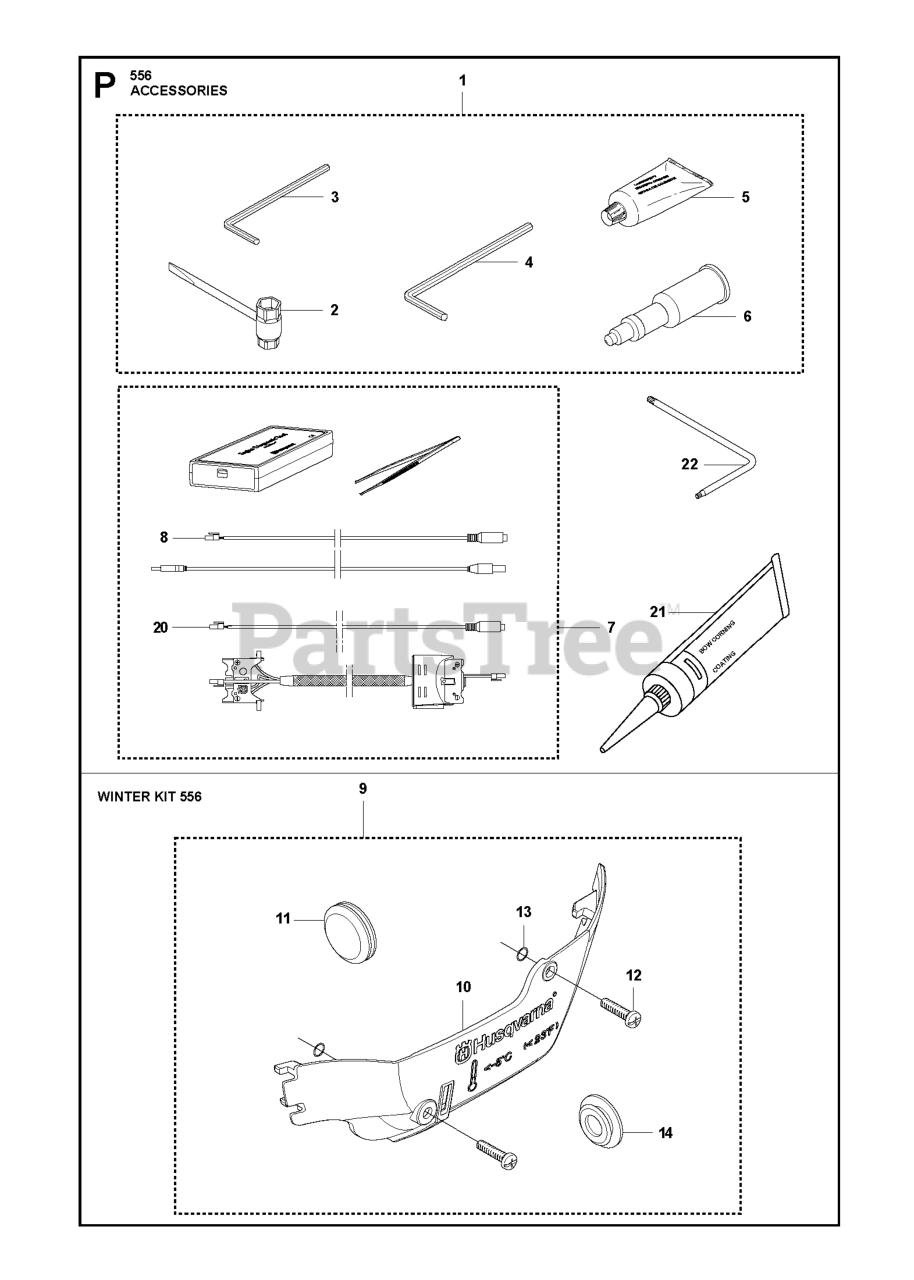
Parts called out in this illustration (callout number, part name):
1	WHEEL.STEER.HUSQ.SR.498.OVMLD
2	COMBINATION WRENCH
2	RP SUBASM.AXLE.CAST.NZTR.
4	SPINDLE WELDMENT.SPINDLE.LH.15
5	GREASE
5	SPINDLE WELDMENT.SPINDLE.RH.15
6	Grease Gun
6	THRUST WASHER
7	DIAGNOSTIC TOOL KIT
8	CABLE ASSY
9	WINTER KIT
9	CAP.SPINDLE.BLACK
10	WINTER COVER
14	WINTER PLUG
14	WASHER, LOCK 3/8
15	NUT CROWNLOCK 3/8-24
16	SHAFT.STEER.2HIGH.SPLND.PLATED
19	PLATE.STEER.DDL.NLT/NG
20	CABLE ASSY
21	ADAPTER.WHEEL.STEER.SPLND.ALUM
22	WRENCH
22	BEARING.SUBASM.SHAFT.STEER.LOW
26	INSERT.CAP.WHL.STRG.HUSQ.PREM
28	SCREW, 3/8-16X3/4
35	GEAR GEAR.SECTOR.TEX.NZTR
45	WASHER 9/16"ID, 2 3/8"OD
50	NUT LOCK FLG 3/8-16 UNC
53	WASHER.HARDENED
57	BRACKET.UPSTOP.TEX
58	BOLT.SHOULDER.SECTOR.P
59	WASHER.THURST.SECTOR.S
60	NUT FLANGE LOCK 5/8-11
61	LINK SUBASM.LINK.DRAG.LH.NZTR
62	TUBE TUBE
63	SCREW
64	RETAINER.CLIP.SPRING.S
66	BOLT HEX FGHD 7/16-14 X 3 SERR
67	BUSHING.PM.FRONT AXLE
68	NUT.LOCK.FLANGE.7/16
69	WASHER.1.5X.505X.118
70	BRKT.DECK.SUSPENSION.F
75	PINION.ZINC PLATED
76	SCREW HEAD SOCKET LRVB
80	THRUST WASHER
81	LINK SUBASM.LINK.CROSS.NZTR
82	SUBASM;PIVOT;BOLT;NZTR
85	PIVOT SUBASM.PIVOT.RH.NZTR
86	PIVOT SUBASM.PIVOT.LH.NZTR
122	CAP.GEAR.SECTOR.TEX
